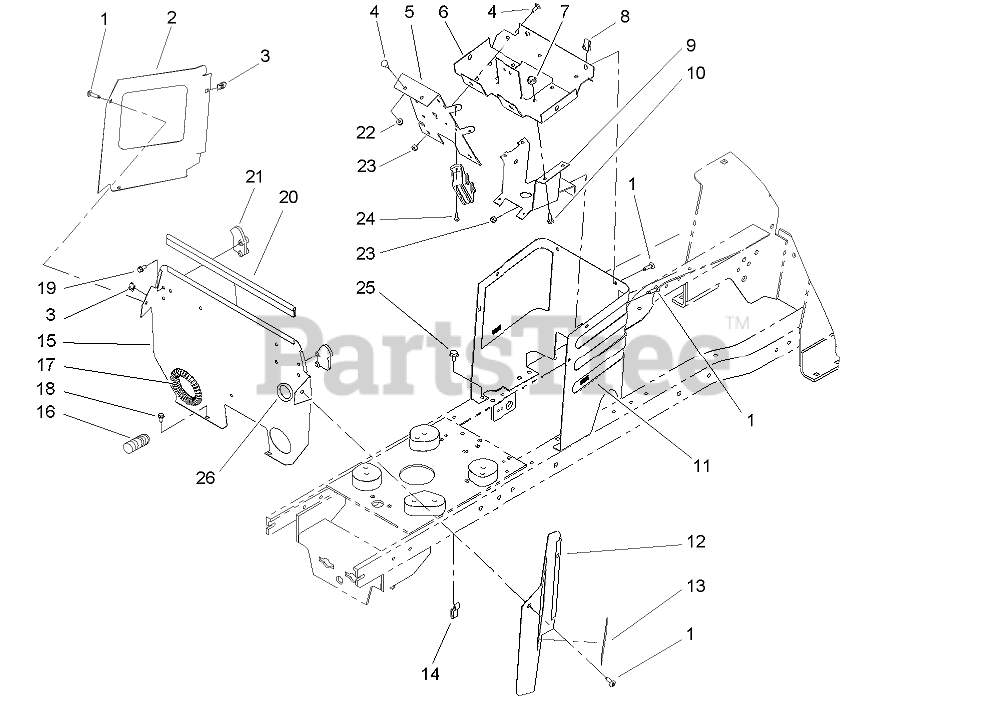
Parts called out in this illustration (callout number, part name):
1	SCREW-HH
2	RH SIDE COVER ASM
4	SCREW-CARR
5	PANEL-SUPPORT, DASH
6	SUPPORT-DASH
7	NUT-HEX
9	BRACKET-COLUMN, LOWER
10	SCREW-HH
11	HOODSTAND ASM
12	LH COVER ASM
14	CLAMP-CASING
15	FIREWALL
16	HARNESS-WIRE
17	COVER-SHAFT, DRIVE
18	SCREW-HWH
19	SCREW-PLASTITE
20	TRIM-SEAL, FIREWALL
21	LATCH-HOOD
22	NUT-KEPS
23	NUT-LOCK, NI
24	SCREW-PPHTF
25	SCREW-HWHTF
26	CONDUIT-ELECTRICAL, CONV, HDPE, BLACK
